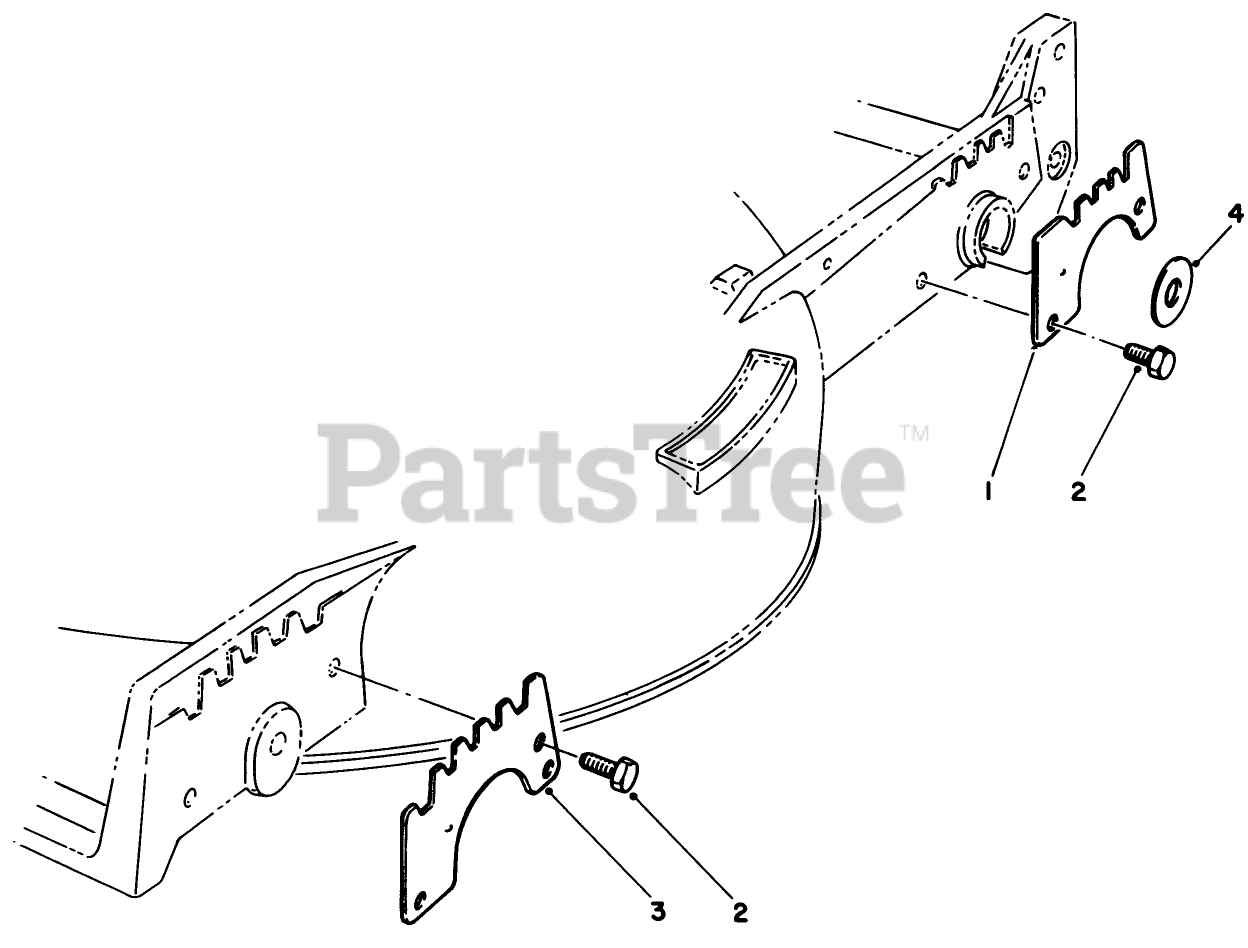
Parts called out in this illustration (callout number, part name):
1	Plate-Wear, Rear
2	SCREW-HWH
3	WEAR PLATE
4	PIVOT WASHER
